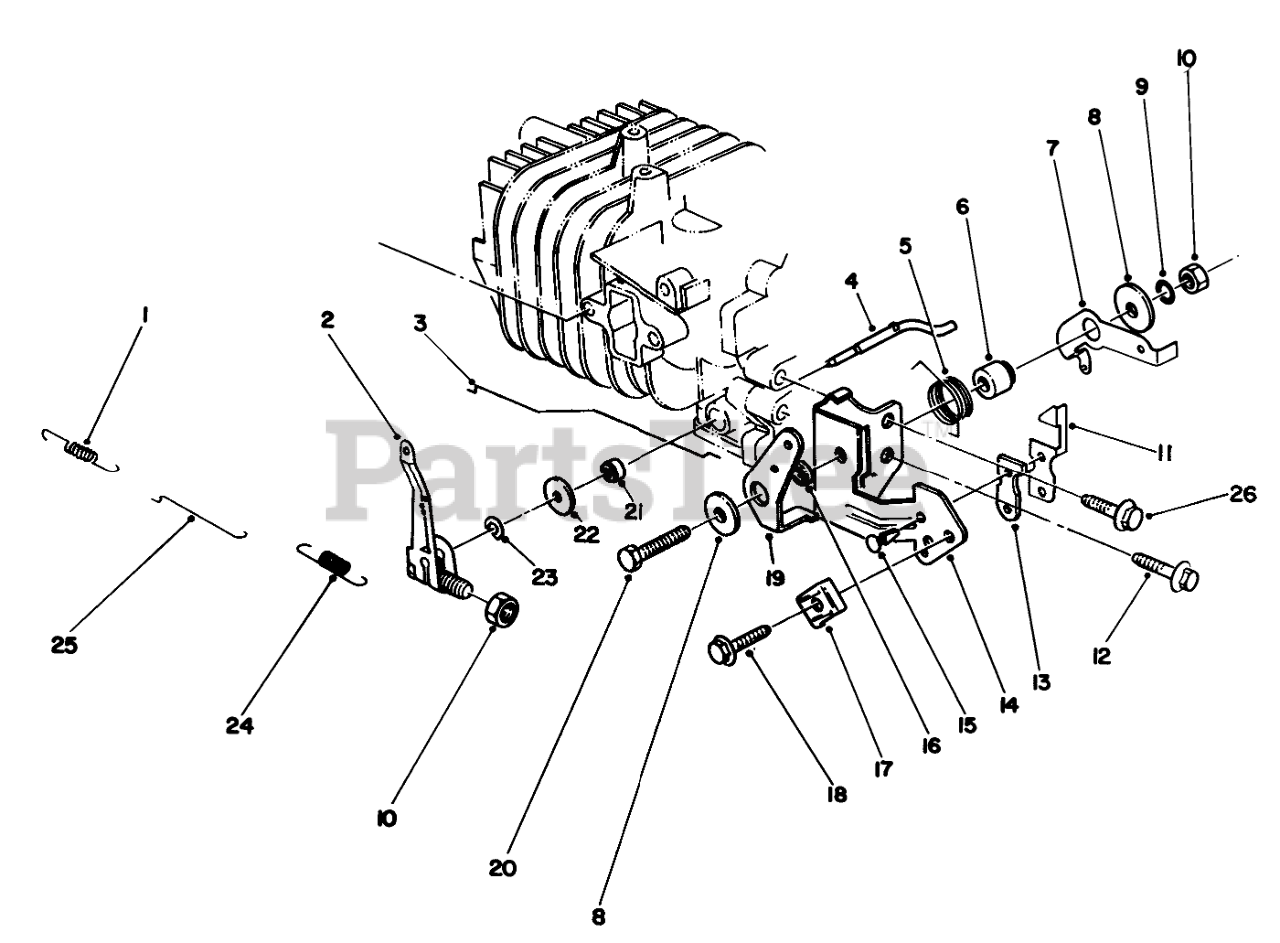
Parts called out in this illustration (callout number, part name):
1	SPRING
2	ARM-GOVERNOR
3	ROD-CHOKE
4	Shaft-Govemor
5	SPRING-CHOKE LEVER
6	Gov Lever Spacer
7	LEVER-SPRING, GOVERNOR
8	WASHER
9	LOCKWASHER
11	TERMINAL-KILL SWITCH
13	INSULATOR-KILL SWITCH
14	BRACKET-THROTTLE, CONTROL
15	RIVET
16	SPACER-CHOKE LEVER
17	CLAMP
19	LEVER-CONTROL, CHOKE
21	SEAL-OIL
22	WASHER
23	E-RING
24	SPRING-GOVERNOR
25	ROD-CARBURETOR
